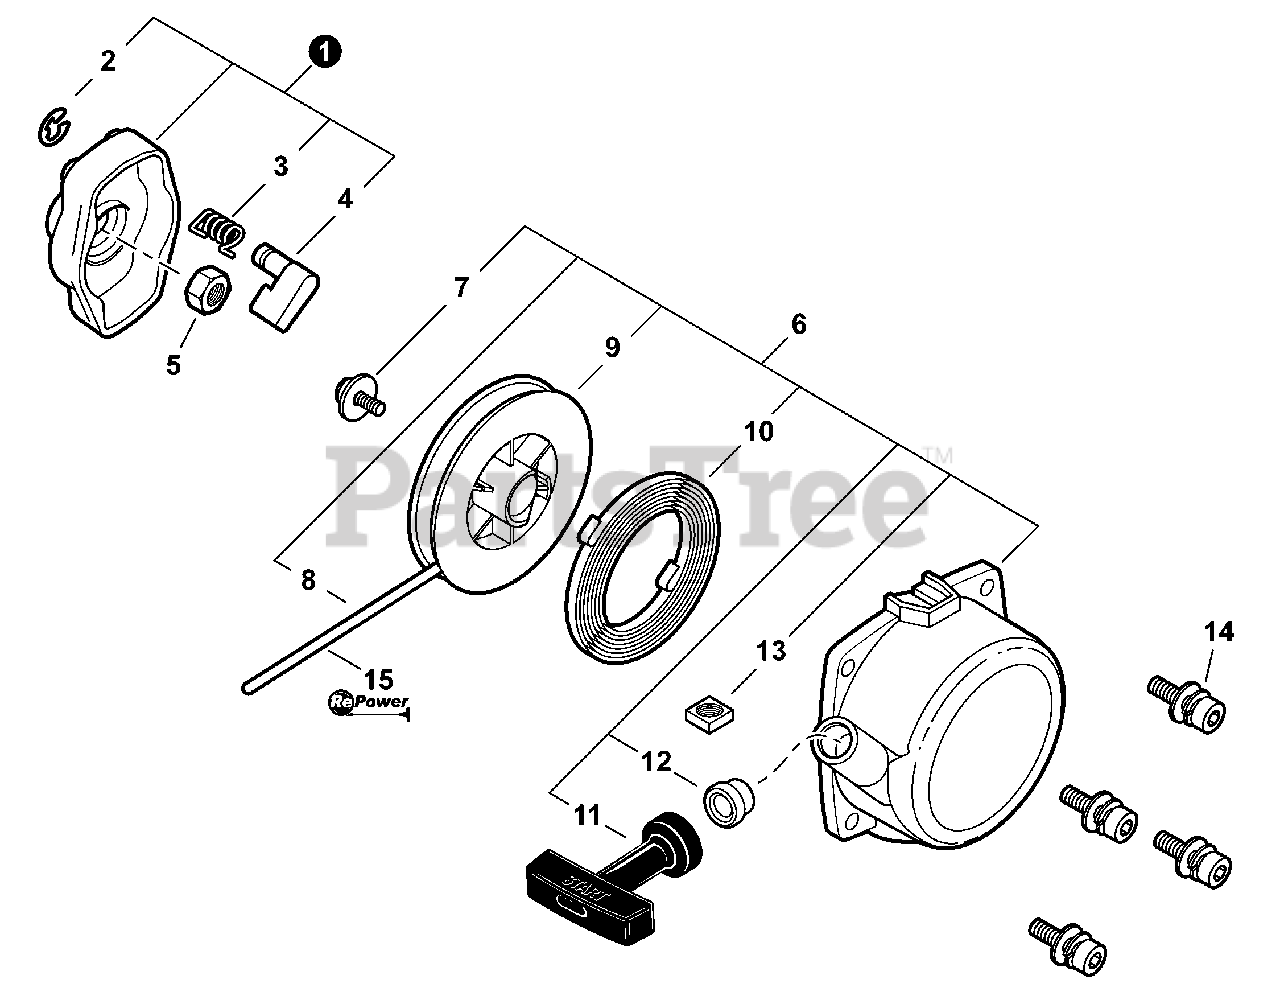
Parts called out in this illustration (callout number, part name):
1	PAWL ASSY, STARTER
2	E-RING 4
3	SPRING, RETURN
4	PAWL, STARTER
5	NUT 8×1.25
6	STARTER ASSY, RECOIL
7	SCREW
8	ROPE, STARTER 3.5×850
9	REEL, ROPE
10	SPRING, RECOIL
11	GRIP, STARTER
12	GUIDE, ROPE
13	NUT M5
14	BOLT 4×12
15	BULK STARTER ROPE - Ø 3.5 MM×61 M
